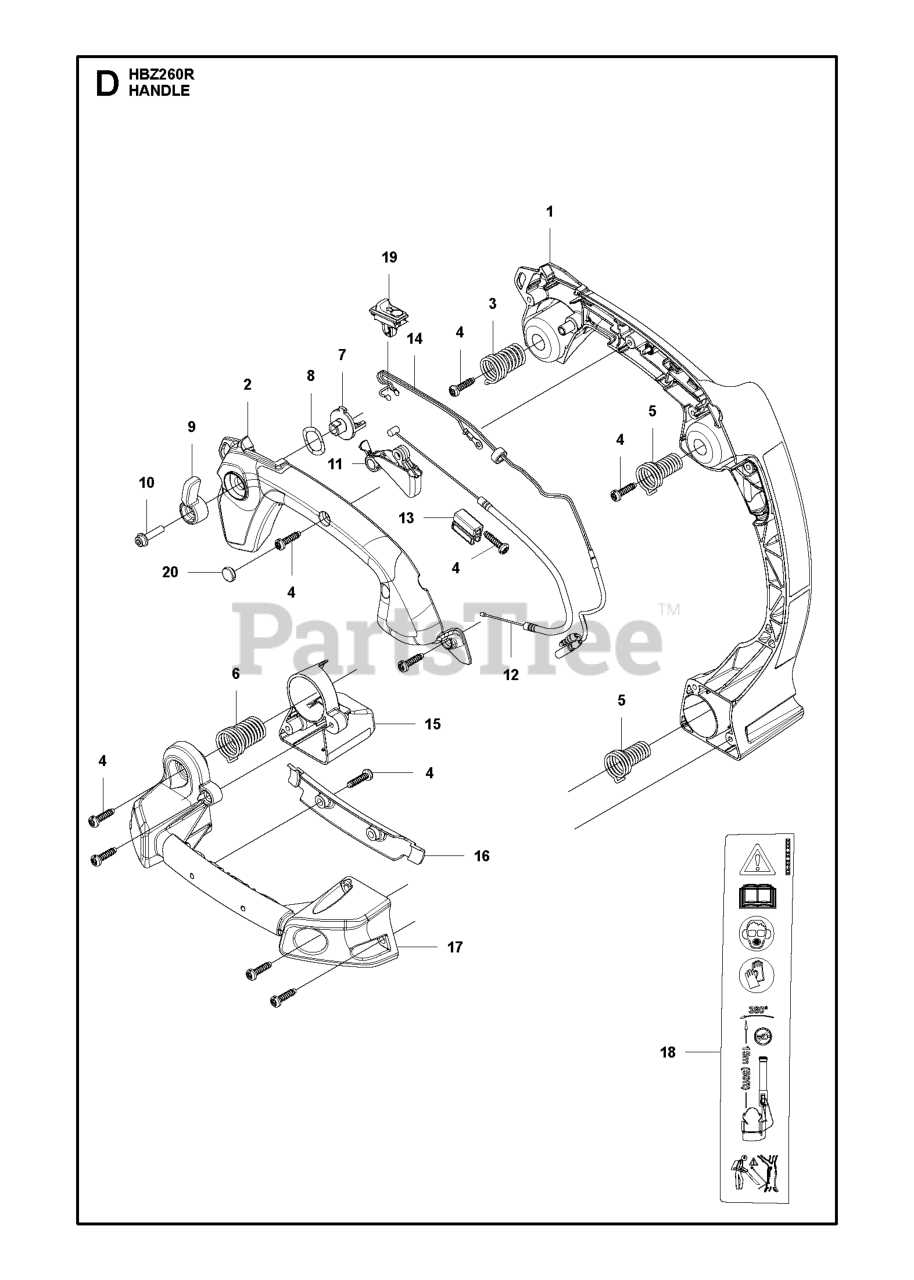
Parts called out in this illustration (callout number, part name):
1	HANDLE RIGHT
2	HANDLE LEFT
4	SCREW, TORX (RPLS T4970-52001)
9	CONTROL LEVER
10	BOLT
11	THROTTLE LEVER
12	THROTTLE CABLE
13	ADJUSTER
14	CORD COMP
15	HANDLE SUPPORT REAR
16	HANDLE SUPPORT COVER
17	HANDLE SUPPORT
18	LABEL WARNING
19	STOP BUTTON
